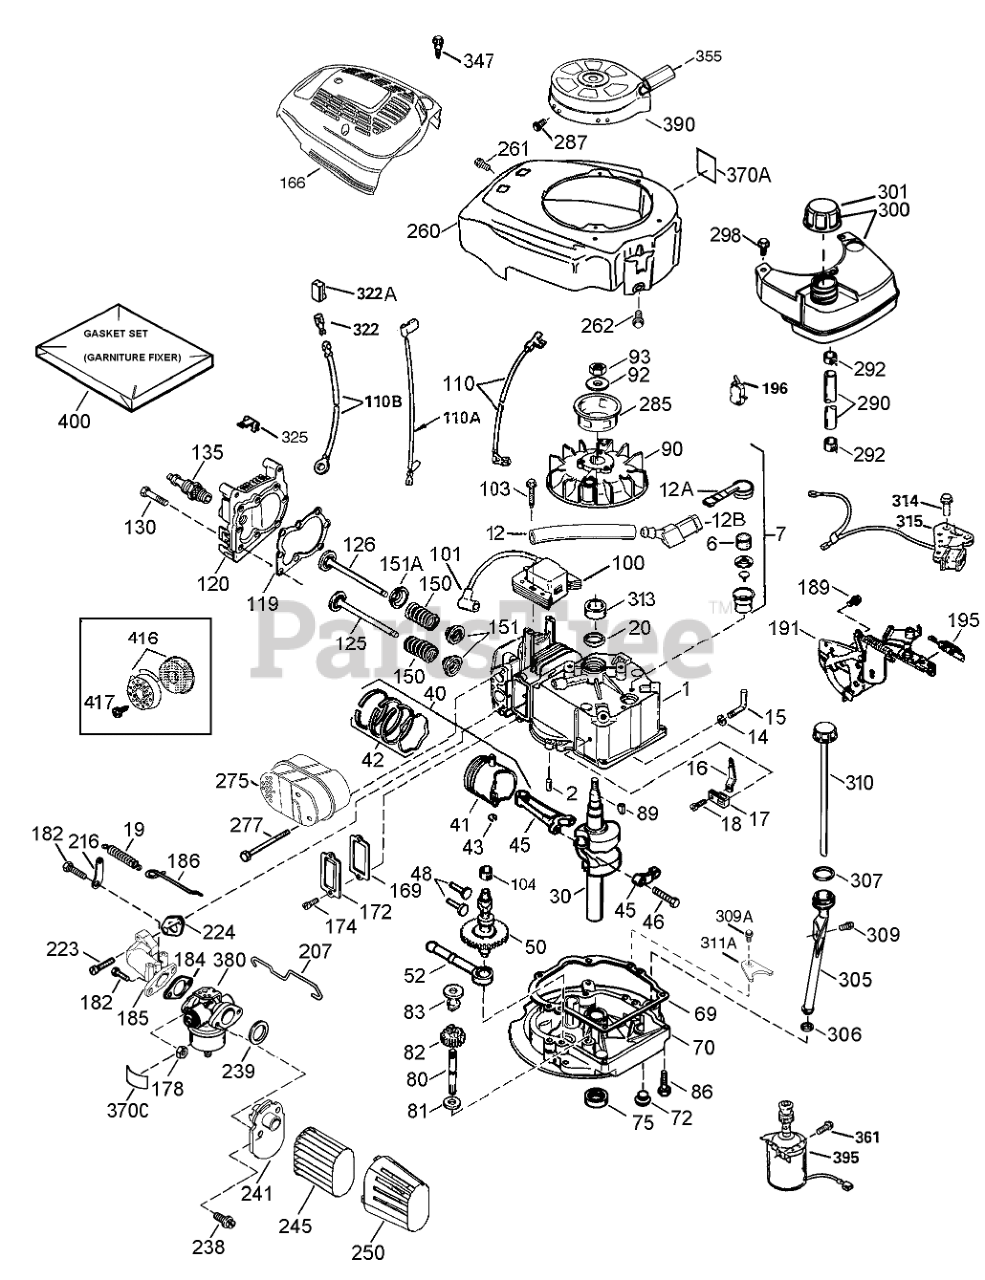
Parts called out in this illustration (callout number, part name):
1	Cylinder (Incl. 2, 20 & 150)
2	Pin-Dowel
6	Element-Breather
7	Breather Ass-y. (Incl. 6 & 12A)
12	Tube-Breather
12A	Breather Cover & Tube (Incl. 12B)
12B	Elbow-Tube, Breather
14	Washer-Flat
15	Governor Rod (Incl. 14)
16	Lever-Governor
17	Clamp-Lever, Governor
18	Screw (T-15, 8-32 x 19/64)
19	Spring-Extension
20	Seal-Oil
30	Crankshaft
40	Piston, Pin and Ring Set (Std.)
41	Piston & Pin Ass-y. (Std.)(Incl. 43)
42	Ring Set (STD)
43	Ring-Retaining, Piston Pin
45	Connecting Rod Ass-y. (Incl. 46)
46	Bolt-Rod, Connecting
48	Lifter-Valve
50	Camshaft (Exhaust MCR)(Inc. 104)
52	Oil Pump ASM
69	Gasket-Flange, Mounting
70	Mounting Flange (Incl. 72-83,306,309A & 311A)
72	Plug-Drain, Oil
75	Seal-Oil
80	Shaft-Governor
81	Washer-Flat
82	Governor Gear Ass-y. (Incl. 81)
83	Spool-Governor
86	Screw (1/4-20 x 1-1/4)
89	Key-Flywheel
90	Flywheel
92	Washer-Belleville
93	Nut-Flywheel
100	Ignition-State, Solid
101	Cover-Spark Plug
103	Screw (T-15, 10-24 x 15/16)
104	Bushing-Cam
110	Wire-Ground
110A	Wire ASM
110B	Wire ASM
119	Gasket-Cylinder Head
120	Head-Cylinder
125	Exhaust Valve (1/32" OS)(Incl. 151)
125	Exhaust Valve (Std.)(Incl. 151)
126	Intake Valve (Std.)(Incl. 151 & 151A)
130	Screw (5/16-18x1-1/2)
135	Spark Plug-Resistor (R J19 L M)
150	Spring-Valve
151	Cap-Valve, Spring
151A	Seal-Valve, Intake
166	Shroud-Engine
169	Gasket-Cover, Valve
172	Cover-Valve
174	Screw (10-24 x 9/16)
178	Nut and Lock Washer (1/4-28)
182	Screw (1/4-28 x 7/8)
184	Gasket
185	Pipe-Intake
186	Link-Governor
191	S.E. Brake Bracket (Incl. 195)
195	Terminal
207	Link-Throttle
216	Lever-Adjusting, R P M
223	Screw (1/4-20 x 1)
224	Gasket-Pipe, Intake
238	Screw (10-32 x 49/64)
239	Gasket-Cleaner, Air
241	Collar-Cleaner, Air
245	Filter-Cleaner, Air (Paper)
250	Cover-Cleaner, Air
260	Housing-Blower
261	Screw (10-24 x 9/16)
262	Screw (1/4-20 x 1/2)
275	Muffler
277	Screw (1/4-20 x 2-9/32)
285	Cup-Starter
287	Screw (8-32 x 21/64)
290	Line-Fuel (8.62)
292	Clamp-Line, Fuel
298	Screw (10-32 x 35/64)
300	Fuel Tank (Incl. 292 & 301)
301	Cap-Fuel
305	Tube-Fill, Oil
306	O-Ring
307	O-Ring
309	Screw (10-32 x 1/2)
309A	Screw (10-24 x 3/4)
310	Dipstick
311A	Bracket-Holddown
313	Spacer
325	Clip-Actuator, Brake Switch
325	Wire Clip
325A	Clip-Wire
347	Screw (10-32 x 27/32)
361	Screw (1/4-20 x 1/2)
370A	Decal-Lubrication
370C	Decal-Primer
370R	Decal-Warning
380	Carburetor (Incl. 184)
390	Rewind Starter ASM
395	12 Volt Electric Starter Motor ASM
400	Gasket Set (Incl. Items Marked PK in Notes)
416	Spark Arrestor Kit
